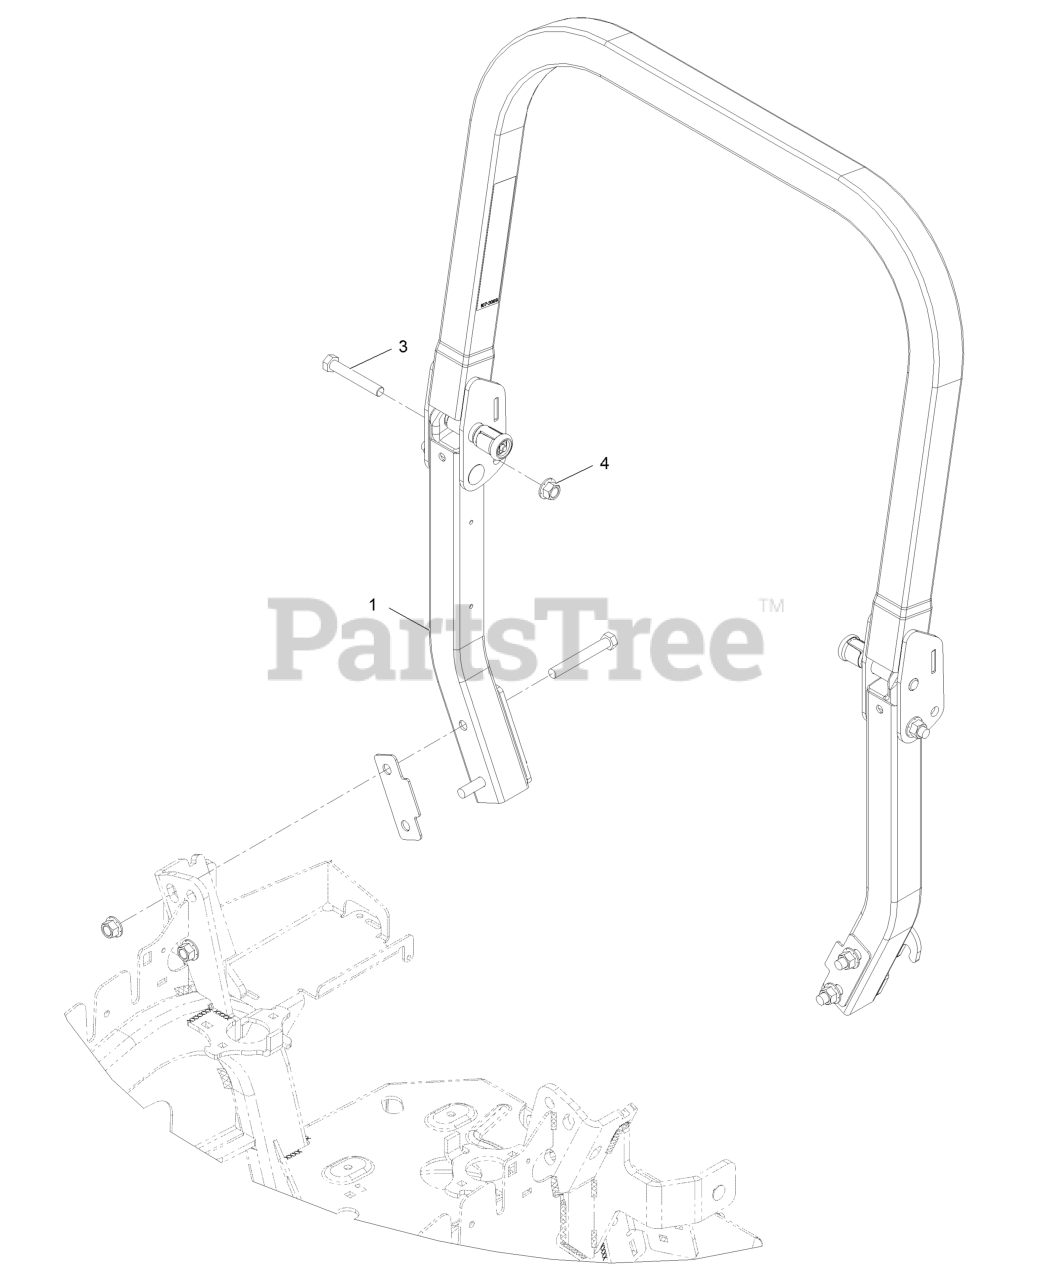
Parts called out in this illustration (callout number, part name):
1	ROPS ASM
3	Screw-HH
4	Nut-Lock
